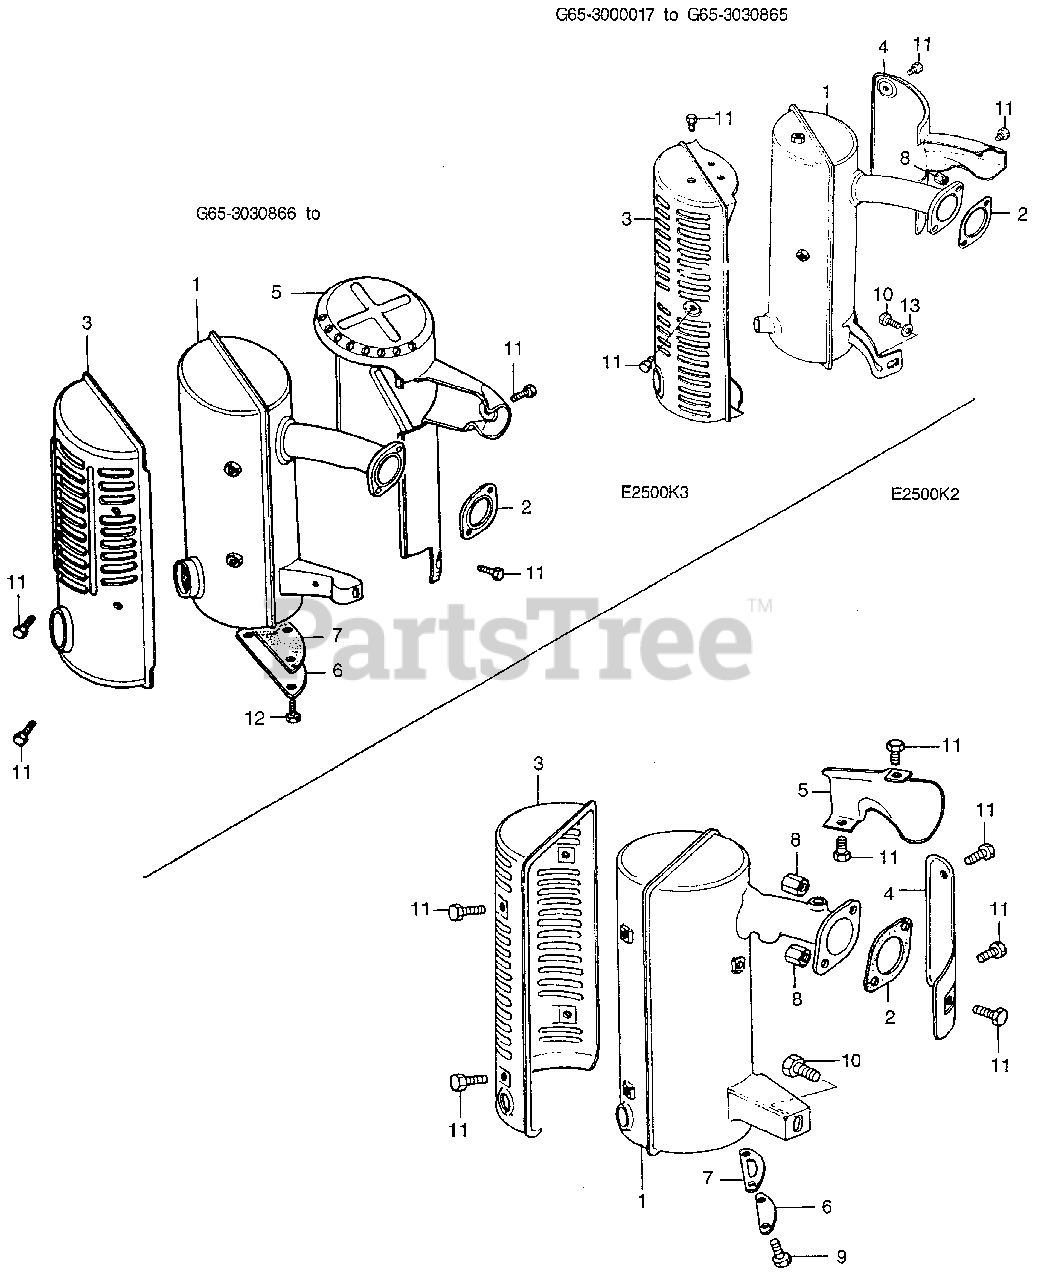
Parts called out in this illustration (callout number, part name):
1	MUFFLER (NOT AVAILABLE)
2	GASKET, MUFFLER (NOT AVAILABLE)
3	PROTECTOR, MUFFLER
4	PLATE, MUFFLER SEPARATOR
5	COVER, EX. PIPE (NOT AVAILABLE)
6	LID, MUFFLER (NOT AVAILABLE)
7	GASKET, MUFFLER LID (NOT AVAILABLE)
8	NUT, HEX. (6MM)
9	BOLT, HEX. (6X8)
10	BOLT, HEX. (8X18)
11	BOLT, HEX. (6X6)
